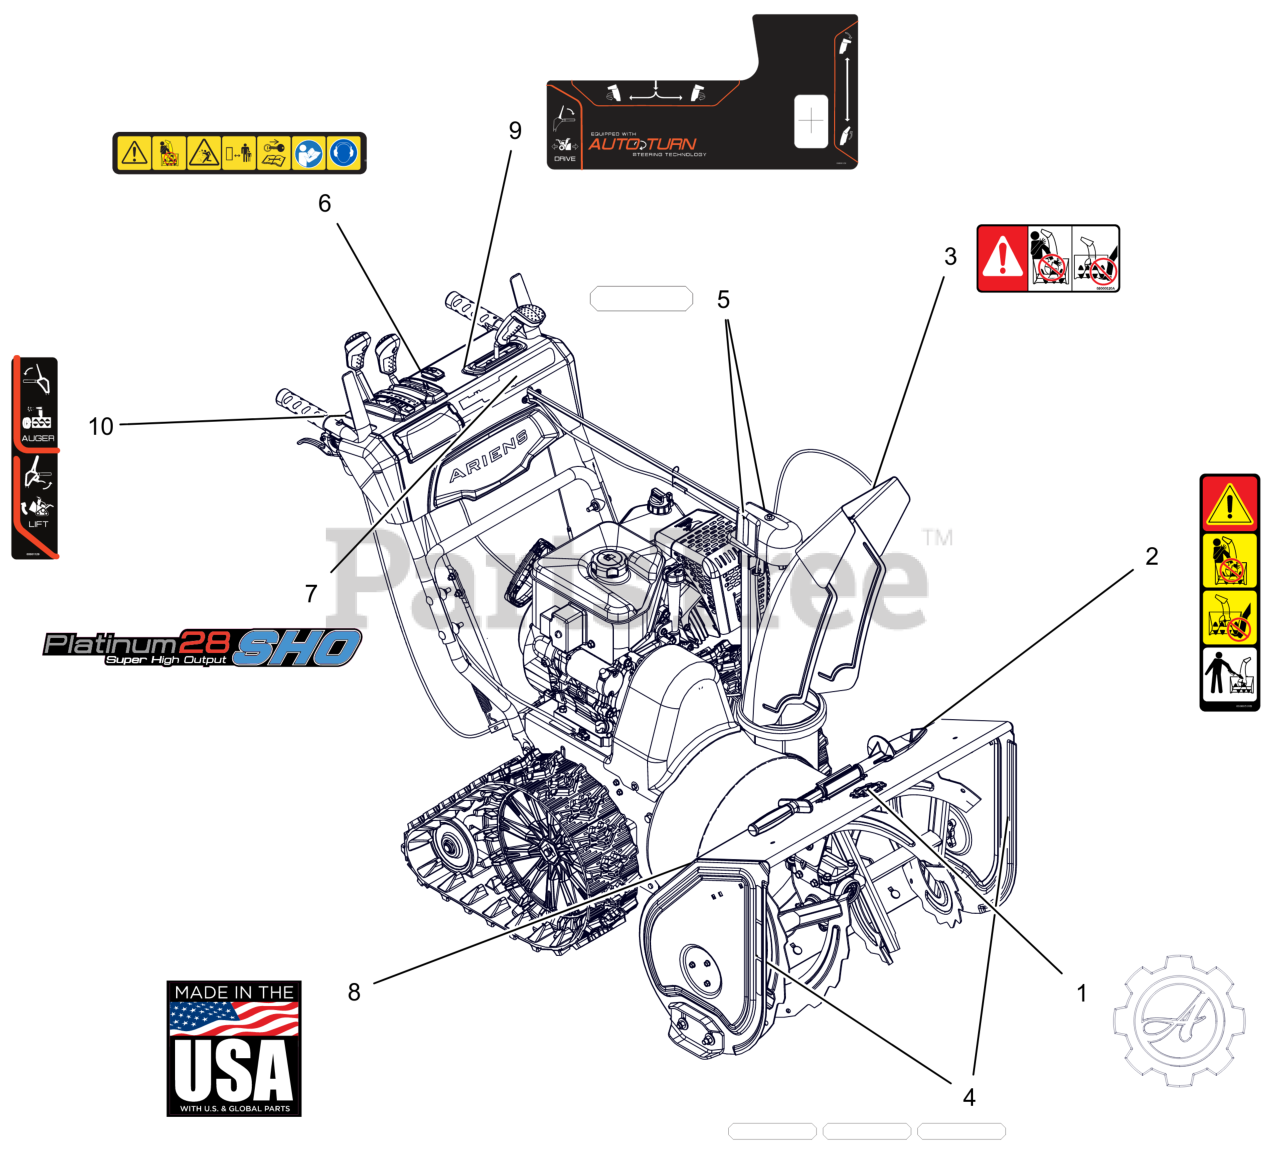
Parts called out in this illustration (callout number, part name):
1	DECAL, ARIENS-GEAR BADGE -THK
2	DECAL, DANGER - ROTATING PARTS
3	DECAL, DANGER
4	DECAL,REFLECTIVE,HOUSING
5	DECAL,REFLECTIVE,GEAR COVER
6	DECAL,DASH - SAFETY
7	DECAL, DASH, PLATINUM 28 SHO
8	DECAL, MADE IN USA
9	DECAL,CONTROL-LG QT2
10	DECAL,CONTROL-RH TRACK
